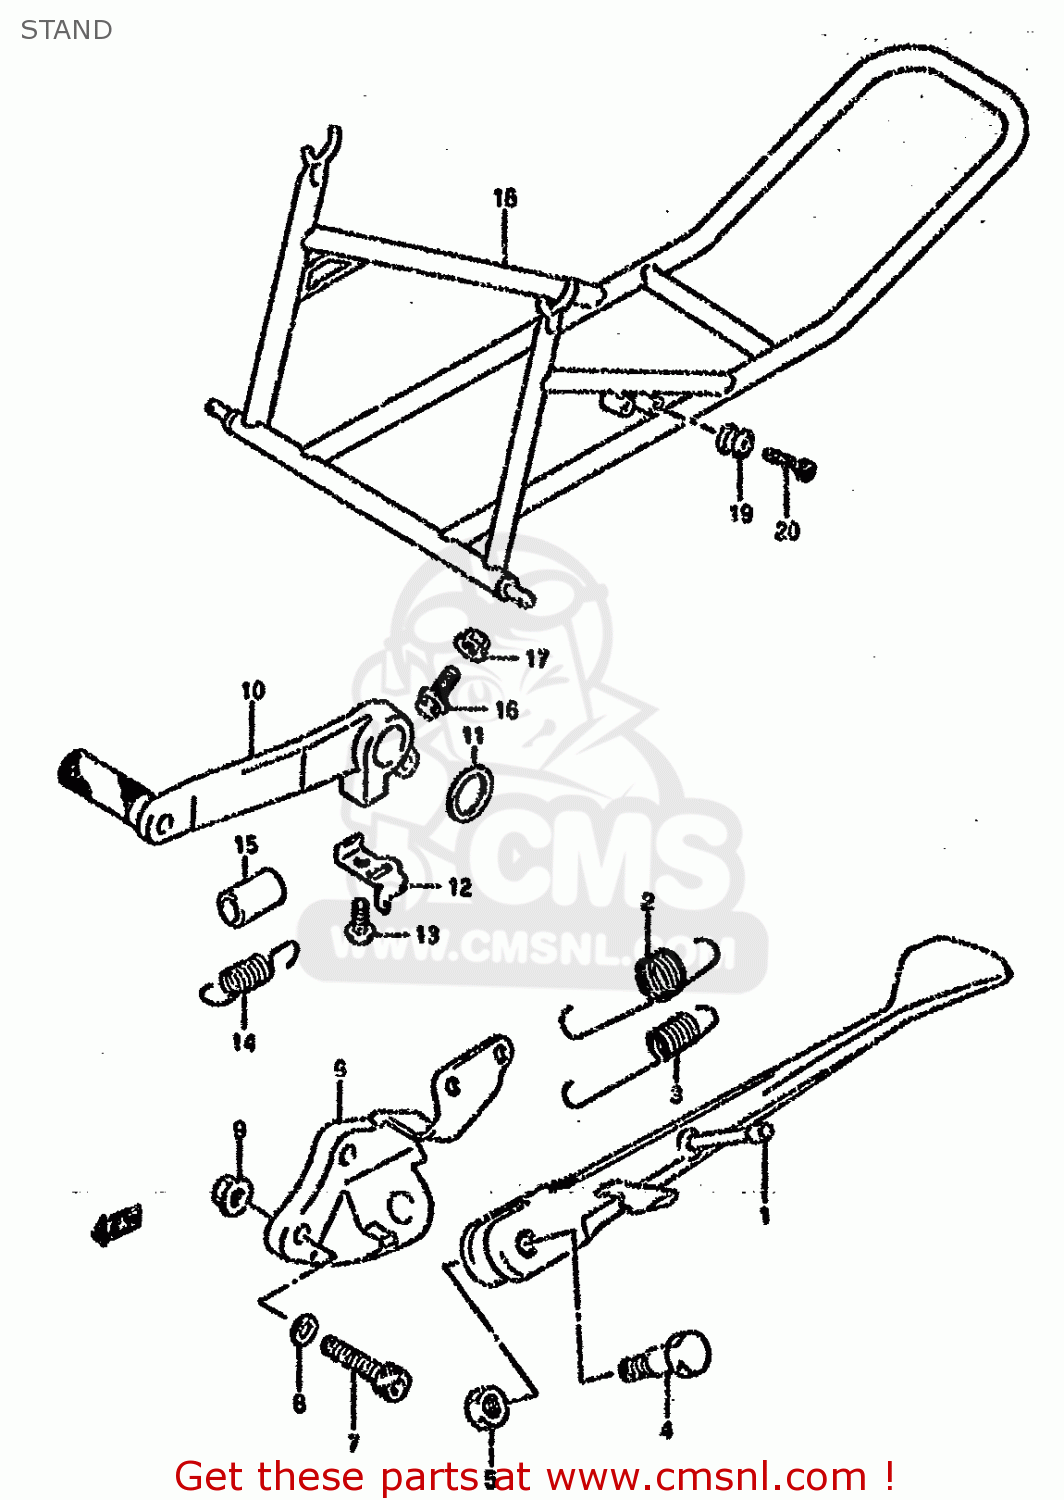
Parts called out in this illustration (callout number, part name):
1	STAND,PROP
2	SPRING,INNER
3	SPRING
4	BOLT(10X38)
5	NUT
6	BRACKET,PROP STAND
7	BOLT
8	WASHER
9	NUT
10	PEDAL,BRAKE
11	WASHER(18X24X1)
12	HOOK,RETURN SPRING
13	BOLT
14	SPRING
15	TUBE,BRAKE SPRING GUIDE
16	BOLT
17	NUT
18	STAND ASSEMBLY,REAR
19	HOLDER,STAND
20	BOLT
